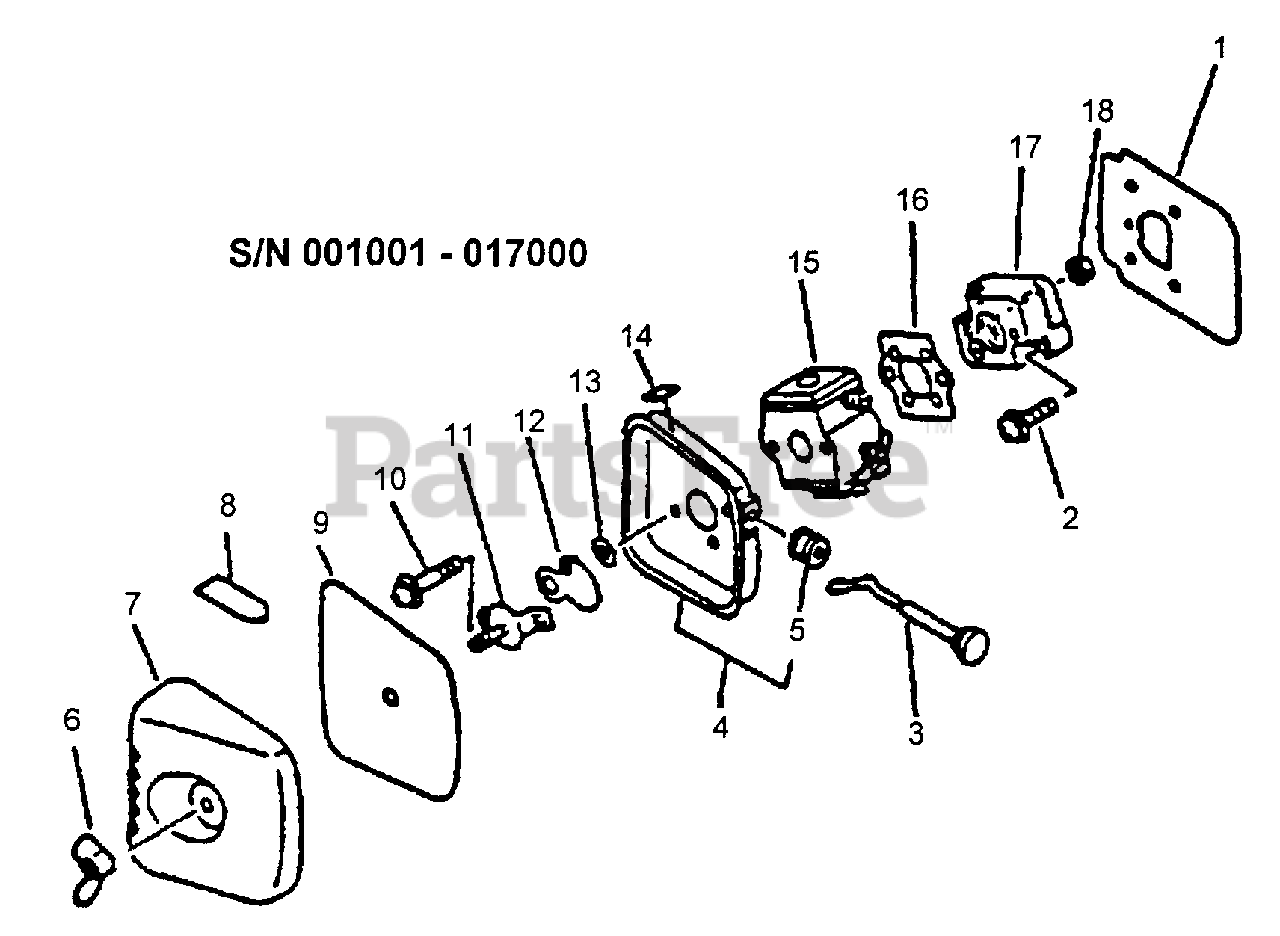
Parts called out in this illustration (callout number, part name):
1	HEAT SHIELD, INTAKE
2	SCREW 5×20
3	ROD, CHOKE
4	CASE, AIR FILTER
5	GROMMET, CHOKE
6	WINGNUT - 6
7	COVER, AIR FILTER
8	LABEL, CHOKE
8	LABEL - CHOKE
9	FILTER, AIR
10	SCREW 5×57
11	PLATE, PREVENT
12	SHUTTER, CHOKE
13	WASHER 5.2×8×0.8T
14	LABEL - IDLE
15	CARBURETOR - C1U-K10
16	GASKET, INTAKE
17	INSULATOR, INTAKE
18	NUT M5
